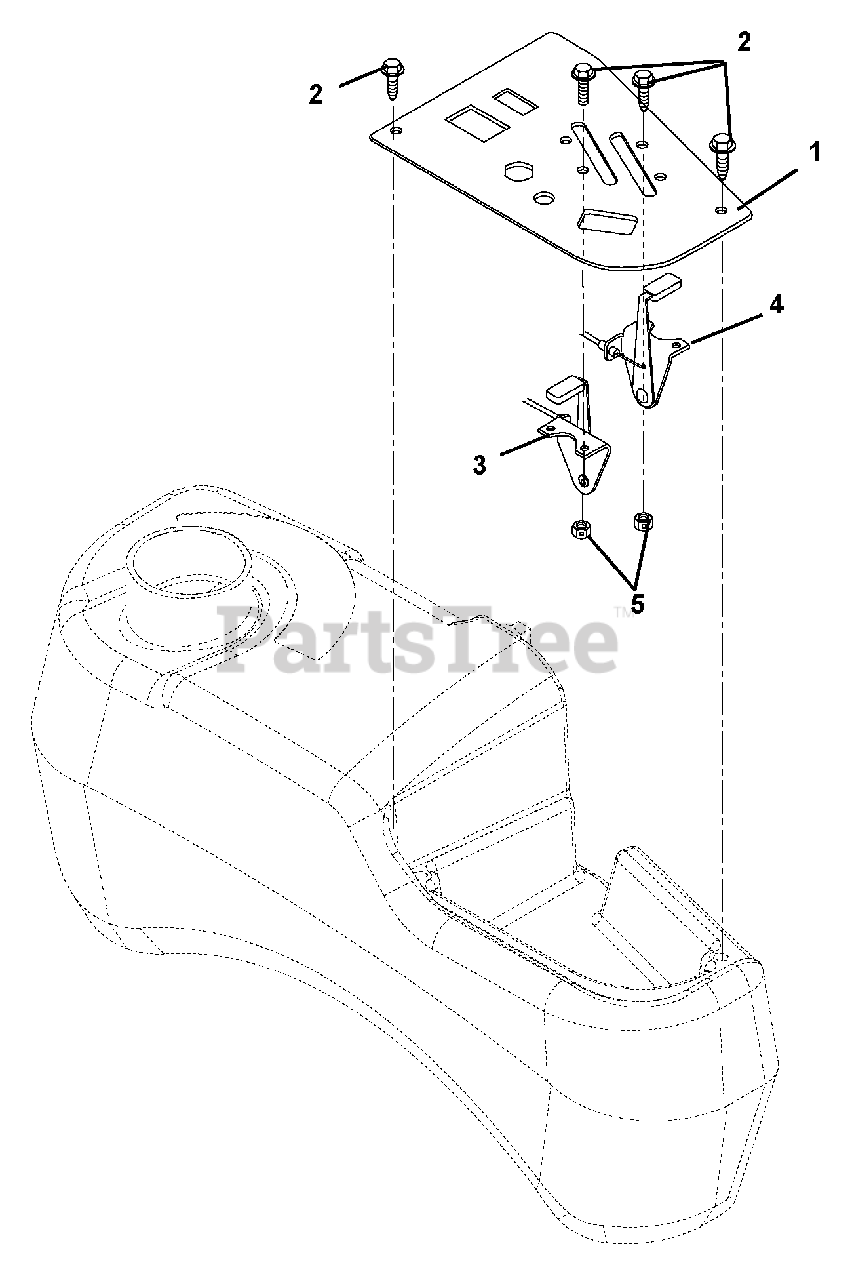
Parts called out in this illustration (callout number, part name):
1	CONTROL PANEL - BLACK
2	@SCR-MCH 10-24X.50 HWH YWZC
3	CABLE, THROTTLE
4	CABLE, CHOKE
5	@NUT-LK-NYL 10-24 W/INSRT YWZC
